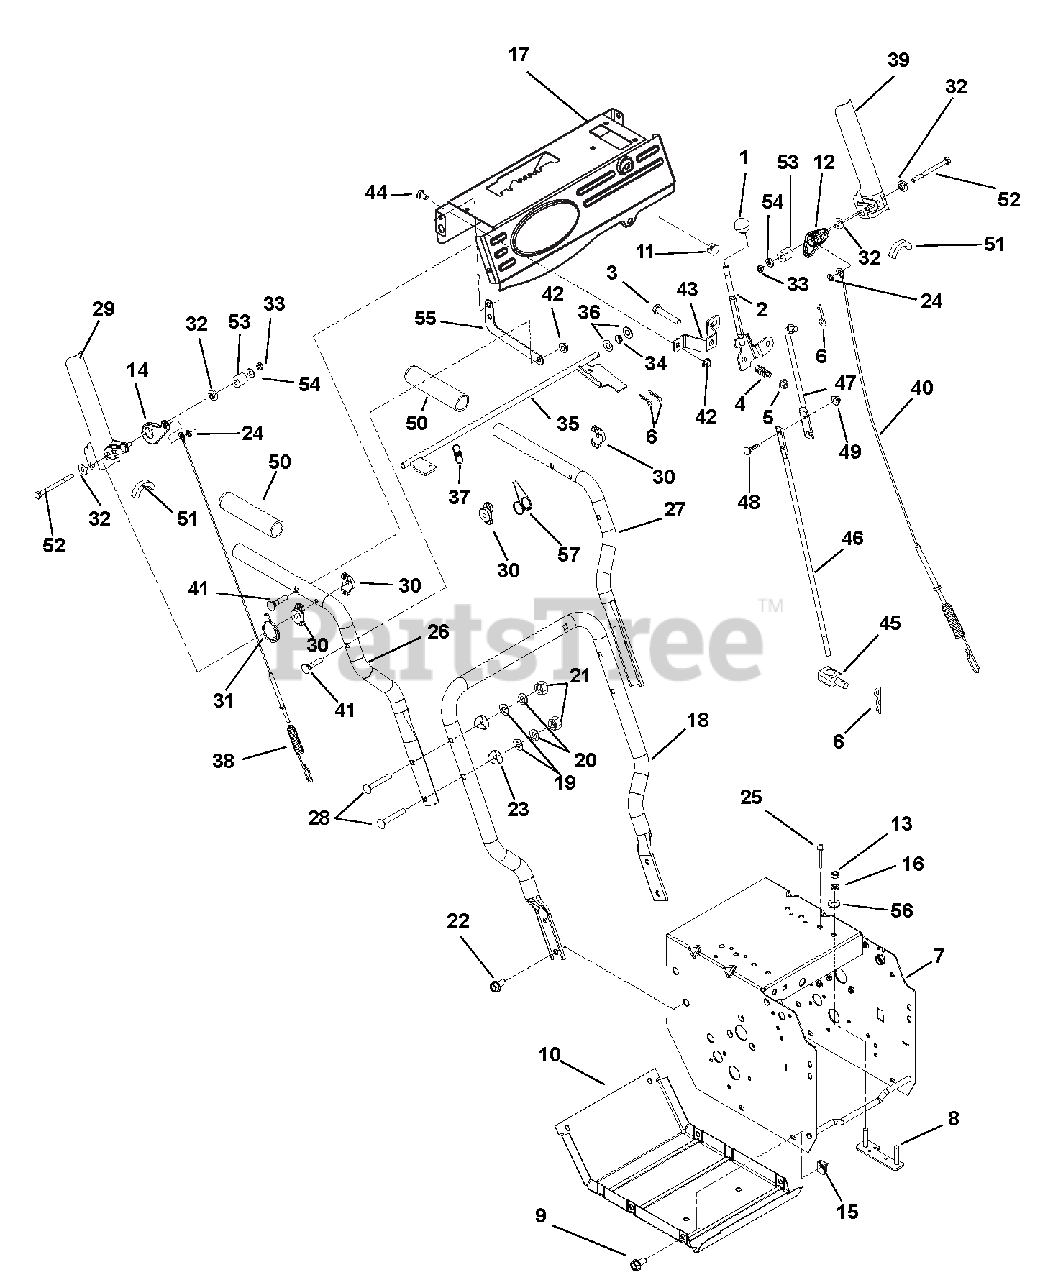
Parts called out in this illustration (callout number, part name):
1	KNOB,BALL -BLACK 1.47" .375-16
2	WMT, SHIFT LEVER
3	@BLT-HEX .38-16X2.00 GR5 YWZC
4	SG-COMP .125X.781X1.250
5	@NUT-LK-TOP-FLG .38-16 YWZC
6	PIN-HAIR INT .08X.18X1.18 YWZC
7	FRAME, 920/921
8	STRAP, ENGINE BOLT-WELDMENT
9	BLT-HEX .25-20X.75 HWH YZ GR5
10	COVER, BOTTOM
11	HOLE PLUG, PLASTIC .44 HOLE
12	CAM, INTERLOCK - LH
13	@NUT-HEX .31-18 YWZC
14	CAM, INTERLOCK - RH
15	NUT-RTNR .25-20X.56
16	WSHR-LK .312X.097 HVY YWZC
17	CONTROL PANEL W/DECAL
18	HANDLEBAR, LOWER (COMPACT)
19	@WSHR-FL-STL.38X.875X.083 YWZC
20	WSHR-LK .312X.097 HVY YWZC
21	@NUT-LK-NYL .312-18 YWZC
22	BLT-SERHFWH .38-16X.75 YWZC
23	SPACER, HANDLEBAR
24	RG-RTNG-EXT .250X.010
25	RVT-POP .187 YZ
26	HANDLEBAR, UPPER - RH COMP/DEL
27	HANDLEBAR, UPPER - LH COMP/DEL
28	@BLT-RDHDSQNK .31-18X2.25 G5YZ
29	PADDLE, CLUTCH - RH COMPACT
30	SPACER, HANDLEBAR
31	SPRING, TORSION
32	BSHG, FLG .266X.42X.150 PM
33	NUT-JAM-NYL .250-20 W/INSERTYZ
34	BUSHING, POLYLINER-.38 SNAPIN
35	WELDMENT, INTERLOCK SHAFT
36	@WSHR-FL-STL.406X.812X.065 YWZ
37	SPRING, EXTENSION
38	CABLE, ATTACHMENT, COMPACT
39	PADDLE, CLUTCH - LH COMPACT
40	CABLE, TRACTION - COMPACT
41	BLT-RDHDXLSQNK .31-18X1.5 G5YZ
42	@NUT-LK-TOP-FLG .31-18 YWZC
43	BRKT, SHIFT MOUNT
44	@BLT-RHDSSQNK .31-18X1.00 G5YZ
45	PIVOT,SHIFT ROD .375-16(TRUNN)
46	ROD, SHIFT - LOWER
47	ROD, SHIFT - UPPER
48	@BLT-RDHDSQNK .25-20X.75 G5YZ
49	@NUT-LK-TOP-FLG .25-20 YWZC
50	HANDLE GRIP
51	EDGING, CLUTCH PADDLE - 2.00"
52	@BLT-HEX .25-20X3.25 YWZC
53	BSHG, SLV .266 X .750 X .750
54	@WSHR-FL-STL.281X.62X.065 YWZC
55	STRAP, SUPPORT - DASH PANEL
56	@WSHR-FL-STL.344X.688X.065YWZC
57	SPRING, TORSION, DUAL COIL
